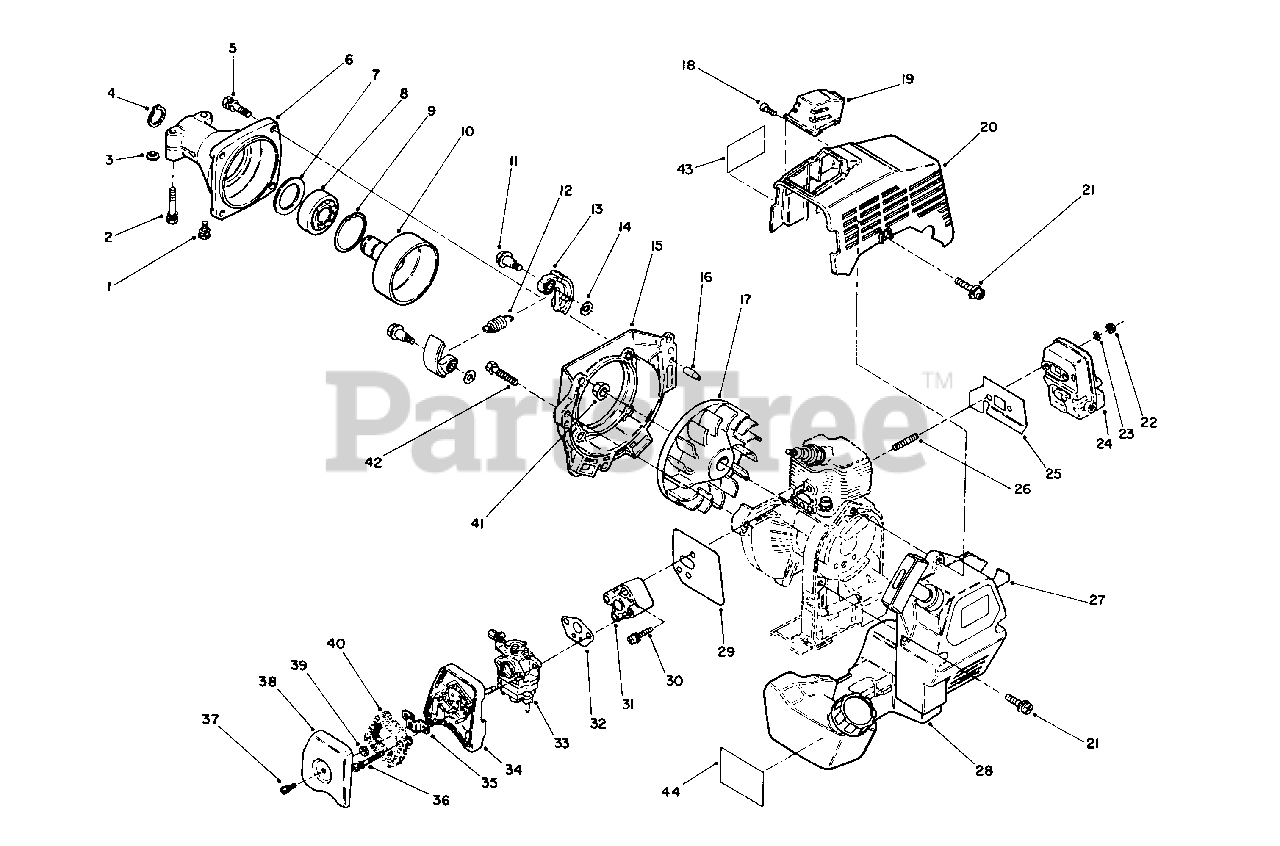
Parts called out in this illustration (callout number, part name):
1	Screw/Washer
2	Bolt/Washer
4	Ring-Retaining
5	Bolt/Washer
6	Case-Clutch
8	Bearing-Ball
9	Ring-Retaining
10	Drum-Cutch
11	Bolt-Clutch
12	Spring
13	Flyweight
15	Case-Fan
16	Pin-Dowel
17	Fan
19	Guard-Spark Plug
20	Cover-Top
21	Screw/Washer
22	Nut-Flange Lock
24	Muffler Assembly
25	Gasket-Muffler
27	Starter-Recoil
28	Tank Assembly-Fuel
29	Gasket-Insulator
30	Screw/Washer
31	Insulator
32	Gasket-Carburator
33	Carburator Assembly
34	Case-Air Cleaner
36	Screw/Washer
37	Screw/Washer
38	Cover-Air Cleaner
40	Element-Air Cleaner
41	Nut-Conical
42	Screw-Pan Hd.
43	Decal-Hot
44	Decal-Fuel Tank
